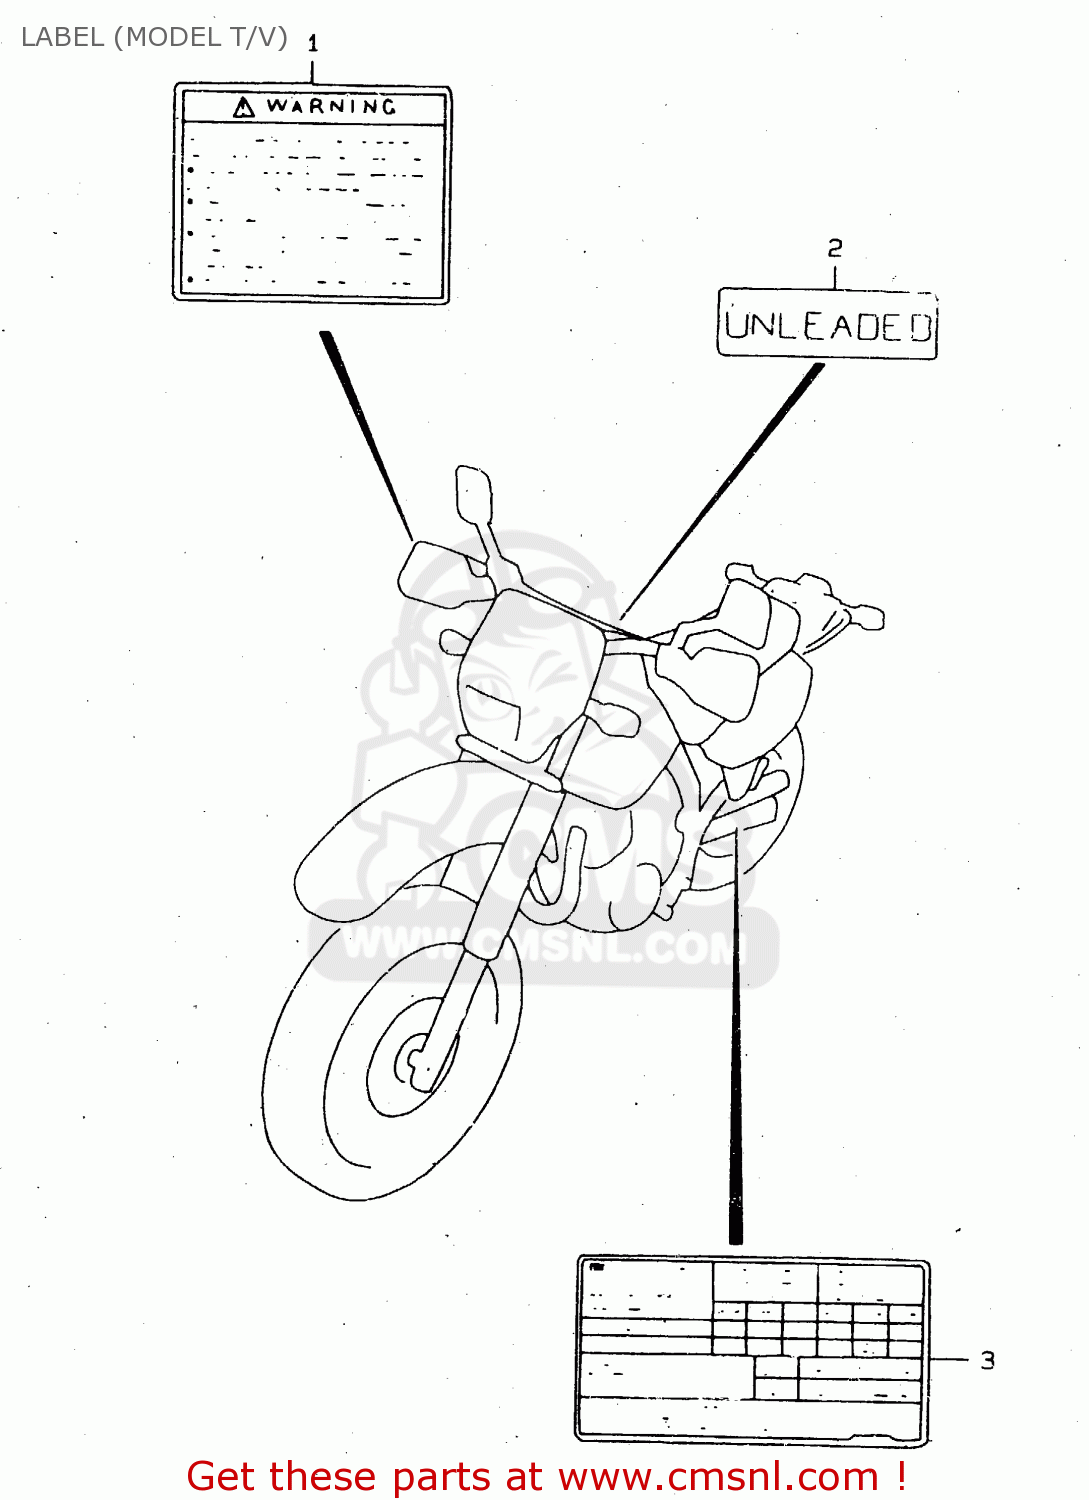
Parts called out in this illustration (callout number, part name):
1	LABEL,WARNING
2	LABEL,CAUTION
3	LABEL,TIRE AIR PRESSURE
4	MANUAL, OWNER'S
